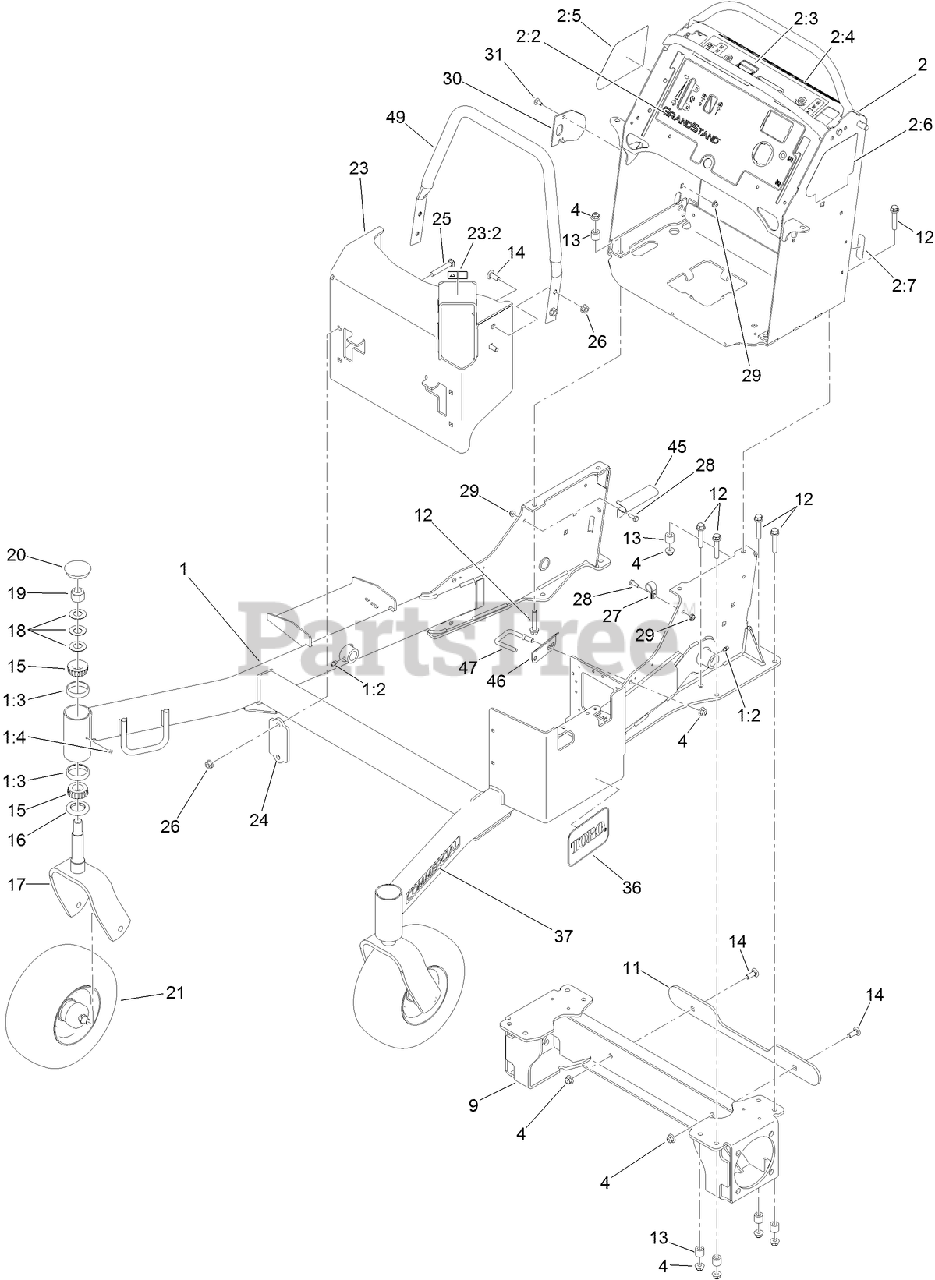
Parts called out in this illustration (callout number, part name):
1	FRONT FRAME ASM
1:2	FITTING-GREASE
1:3	CUP-BEARING
2	CONTROL TOWER ASM
2:2	DECAL-PANEL, CONTROL
2:3	DECAL-OPC
2:4	DECAL-WARNING
2:5	DECAL-HOC
2:6	DECAL-SERVICE/SPARK ARREST
2:7	DECAL-FUSE
4	NUT-HF, NI
9	FRAME-MOTOR
11	PLATE-SPACER, BUMPER
12	SCREW-HHF
13	SPACER
14	SCREW-CARR
15	BEARING-ROLLER, TAPERED
16	SEAL-GREASE
17	FORK-CASTER
18	WASHER-BELLVILLE
19	NUT-LOCK, NI
20	CAP-GREASE
21	WHEEL/TIRE AND BEARING ASM
23	MUFFLER GUARD ASM
23:2	DECAL-WARNING
24	BRACKET-MOUNTING, GUARD
25	SCREW-CARR
26	NUT-HF
27	CLAMP-CABLE
28	SCREW-HH
29	NUT-HF
30	PLATE-STRIKER
31	SCREW-CARR
36	DECAL
37	DECAL-COMMERCIAL
45	BRACKET-HOSE, FUEL (DOUBLE)
46	GUARD-HOSE
47	GUIDE-HOSE
49	TUBE-GUARD
